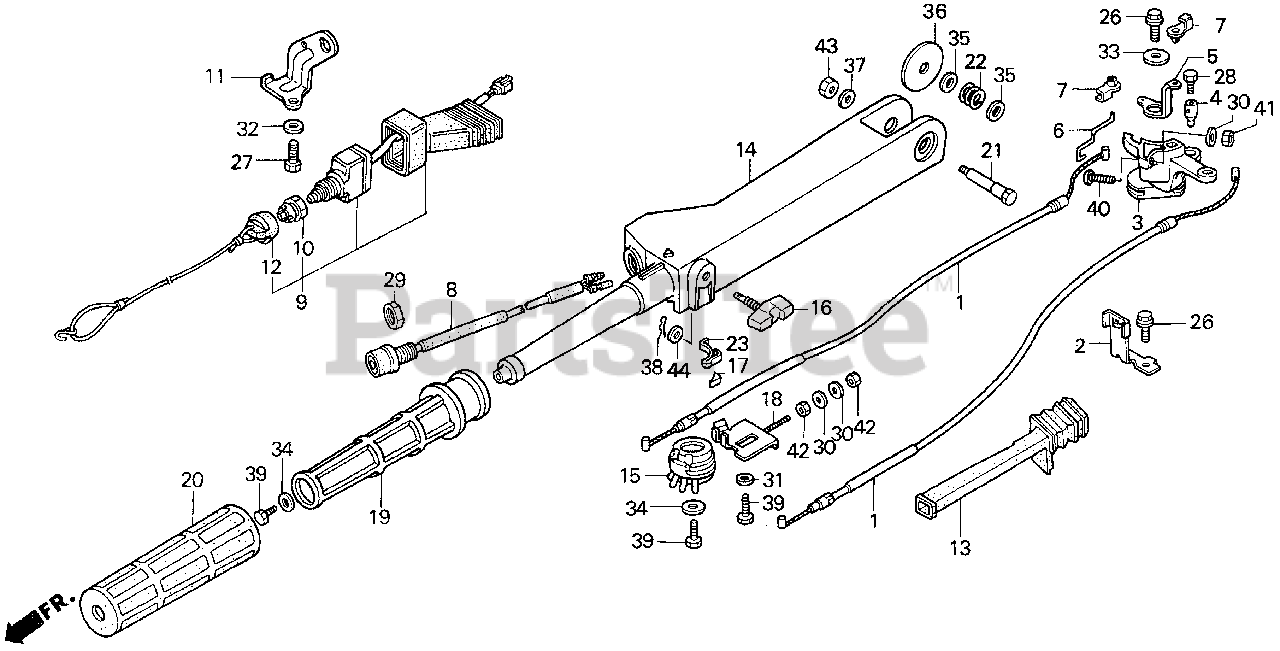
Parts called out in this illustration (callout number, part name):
1	CABLE, THROTTLE
2	CLAMP, THROTTLE CABLE
3	ARM, THROTTLE
4	HOLDER, THROTTLE ROD
5	ARM, CHOKE
6	ROD, CHOKE KNOB
7	BUSH, LINKAGE
8	SWITCH ASSY., STOP
9	SWITCH ASSY., EMERGENCY STOP
11	BRACKET, EMERGENCY STOP SWITCH (NOT AVAILABLE)
13	GROMMET, OIL CASE (A)
14	HANDLEBAR *NH210MC* (AQUA SILVER METALLIC-C)
15	REEL, CABLE
16	BOLT, FRICTION
17	BLOCK, THROTTLE FRICTION
18	PLATE, ADJUSTING
19	PIPE, GRIP
20	RUBBER, GRIP
21	SCREW, HANDLE PIVOT
22	SPRING, HANDLE PIVOT
23	SPRING, THROTTLE FRICTION
26	BOLT, FLANGE (6X12)
27	BOLT, HEX. (6X14)
28	BOLT, RECESSED (5X8)
29	NUT, HEX. (16MM)
30	WASHER, PLAIN (5MM)
31	WASHER, PLAIN (6MM)
32	WASHER, PLAIN (6MM)
33	WASHER, PLAIN (6MM)
34	WASHER (6MM)
35	WASHER (10MM)
36	WASHER, HANDLEBAR
37	WASHER, PLAIN (8MM)
38	PIN, SPLIT (2.0)
39	BOLT, HEX. (6X12)
40	SCREW, PAN (5X40)
41	NUT, HEX. (5MM)
42	NUT, HEX. (5MM)
43	NUT, HEX. (8MM)
44	WASHER, PLAIN (5MM)
44	WASHER, FLAT (4MM)
